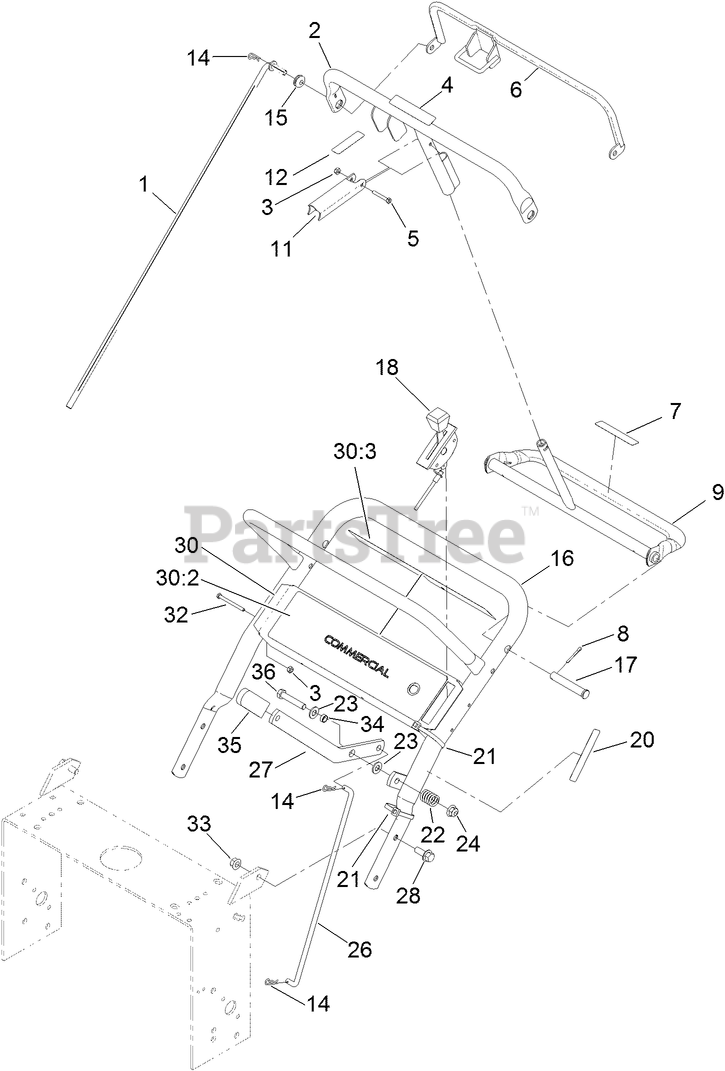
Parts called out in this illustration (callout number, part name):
1	ROD-CONTROL
2	BAR-CONTROL
3	NUT-LOCK, NI
4	DECAL-BAR, CONTROL
5	SCREW-SHH
7	DECAL-REVERSE
8	PIN-COTTER
9	PIVOT-CONTROL
11	LEVER-BRAKE, PARKING
12	DECAL-LEVER, PARKING
14	PIN-COTTER
15	GROMMET-RUBBER
16	HANDLE-UPPER
17	PIN-CLEVIS
18	CABLE-THROTTLE
20	DECAL-ENGAGE, DECK
21	TIE-PLASTIC
22	SPRING-COMPRESSION
23	WASHER-FLAT
24	NUT-HF, NI
26	LINKAGE-DRIVE, BLADE
27	LEVER-ENGAGEMENT, BLADE
28	SCREW-HHF
30	CONTROL PANEL ASM
30:2	DECAL-PANEL, CONTROL
30:3	DECAL - WARNING, CONTROL
32	SCREW-SHH
33	NUT-HF
34	SPACER
35	GRIP-LEVER
36	SCREW-HH
